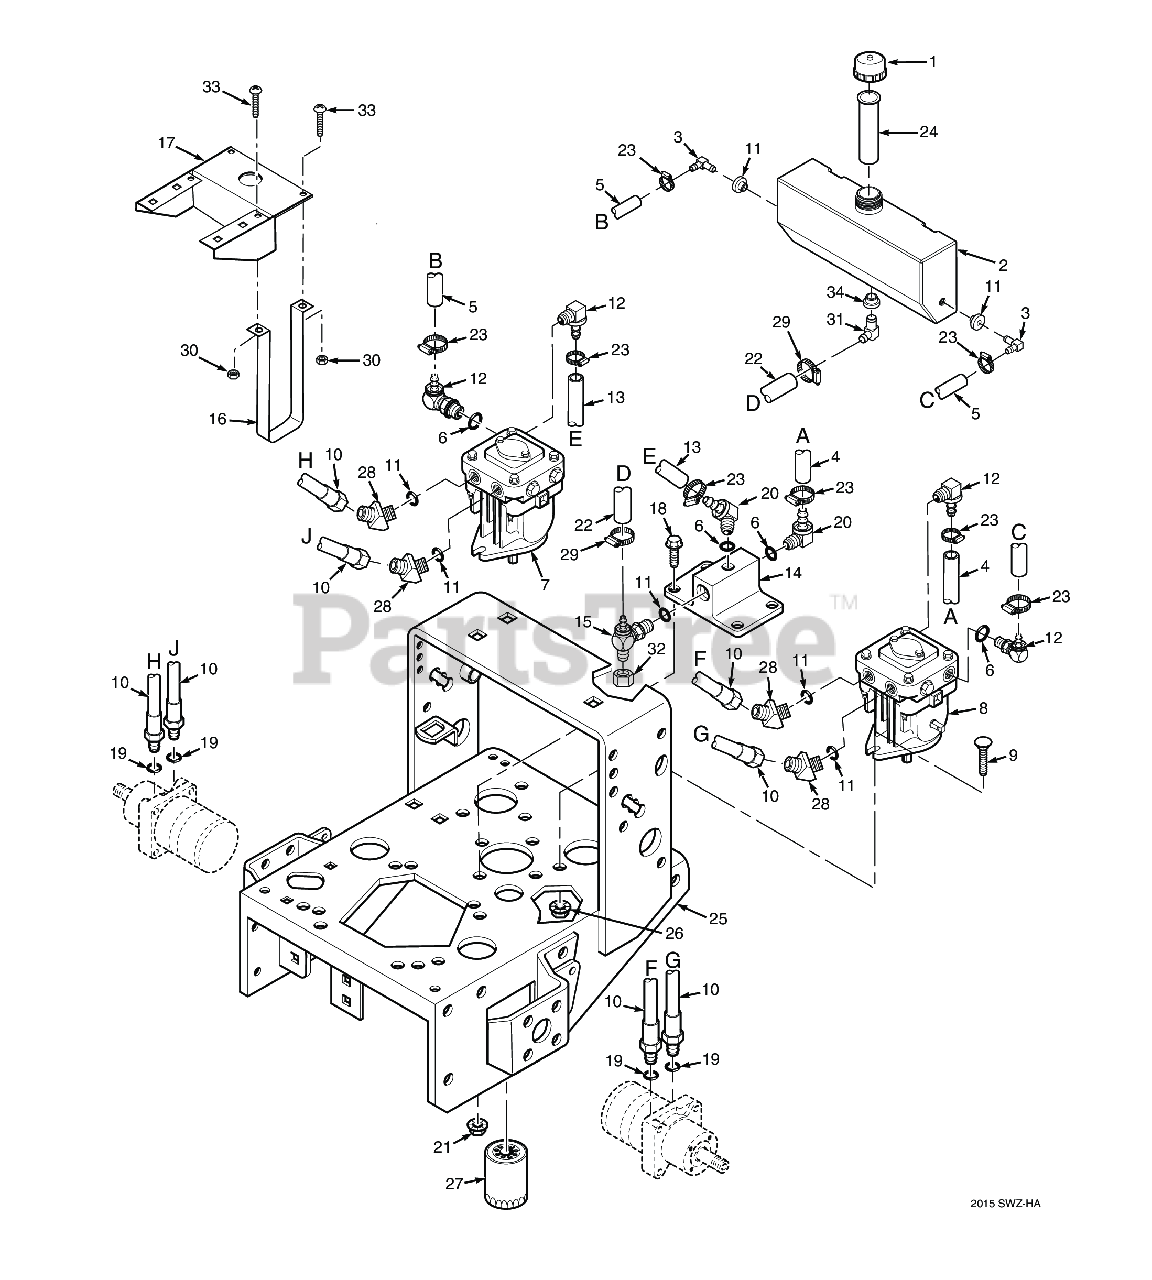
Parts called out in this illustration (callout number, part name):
1	CAP, HYDRAULIC TANK
2	Oil Reservoir (With Fittings)
3	Elbow, 90 Degree, 9/16-18 JIC x 9/16 O-Ring
4	Hose, 3/8" ID - 10-1/4" Long (Order By The Inch)
5	Hose, 3/8" ID - 10-1/4" Long (Order By The Inch)
6	"O" RING, 5/64 X 15/32 ID
7	Pump, PG-1JQQ-DY1X-XXXX (R.H.)
8	Pump, PG-1GQQ-DY1X-XXXX (L.H.)
9	SHORT SQ. NECK CARRIAGE BOLT, 3/8-16 X 1-1/4"
10	Hose, Pump to Wheel Motor
11	Bushing, 0.56" Dia. Viton
12	Elbow, 90 deg. 7/16-20 JIC to 9/16-18 "O" Ring
13	Hose, 3/8" ID - 10-1/4" Long (Order By The Inch)
14	Filter Head Assembly
15	Tee, 3/8" O-Ring x JIC x 1/2" Hose
16	Strap, Hydraulic Tank
17	Bracket, Hydraulic Tank
18	Capscrew, 5/16-18 x .75 Serrated Flange Hex Head
19	"O" RING, 3/32 X 3/4 ID
20	Elbow, 90 Degree - 9/16" O-Ring x 3/8" Hose
21	Nut, Serrated Flange 5/16-18 (Right Front Engine Mounting, Briggs and Kohler Only)
22	Hose, Formed 1/2" ID
23	Clamp, .69" Max. / .25" Min. Dia.
24	Insert, Filler Neck
25	Engine Deck (16" Wide) with Decals - Small Frame
25	Engine Deck (20" Wide) with Decals - Large Frame
26	NUT, 3/8-16 SERRATED FLANGE HEX HEAD
27	OIL FILTER, SPECIAL
28	Elbow, 45 Deg. - 3/4-16 JIC Male x Male 3/4-16 O-Ring
29	Clamp, Cable 3/4" I.D.
30	HEX, NUT, ELASTIC STOP LOCK, 1/4-20
31	Fitting, 90 Degree - 1/2" Hose
32	CAP, 3-4-16 JIC
33	Machine Screw, Round Head, 1/4-20 x 2.00"
34	Bushing, 0.78" Dia. Viton
